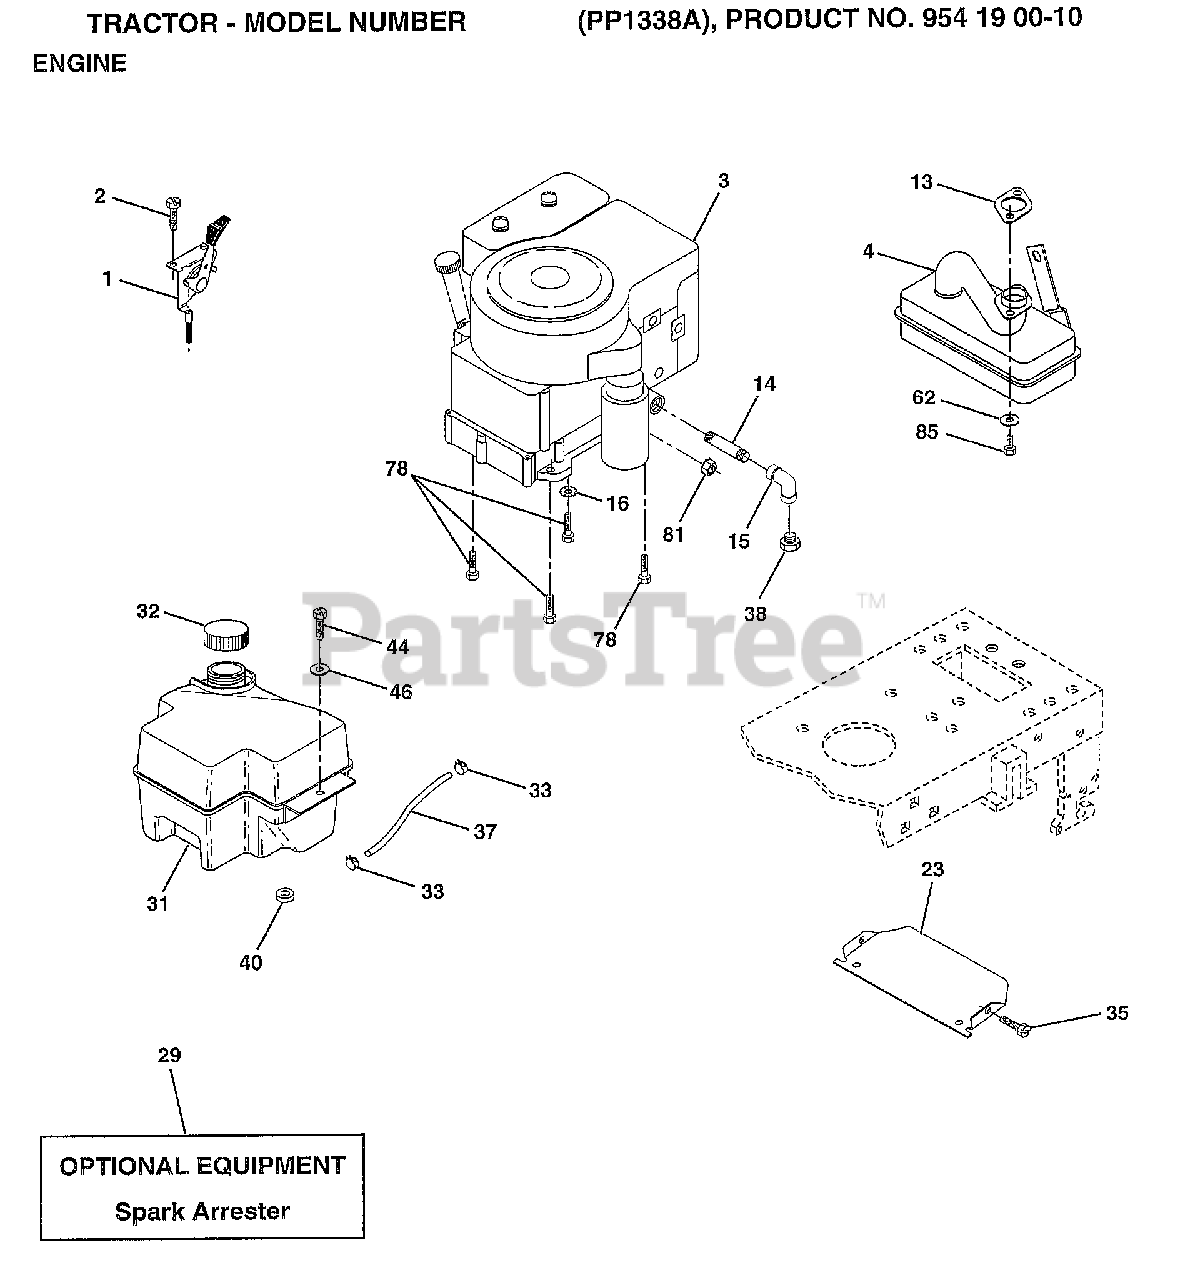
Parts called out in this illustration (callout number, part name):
1	CONTROL-THROT/CHO
2	SCREW LT
4	MUFFLER TEC. 13HP
13	GASKET ENG 1 313 LD TIN PLATED
14	PIPE NIPPLE LT
15	ELBOW
16	LOCKWASHER
23	SHIELD-HEAT
32	CAP ASM FUEL
33	HOSE CLAMP
35	SCREW
37	LINE FUEL
44	SCREW HEX CRT
46	WASHER
62	LOCKWASHER
78	SCREW
81	NUT
85	SCREW HEX HD CAP
